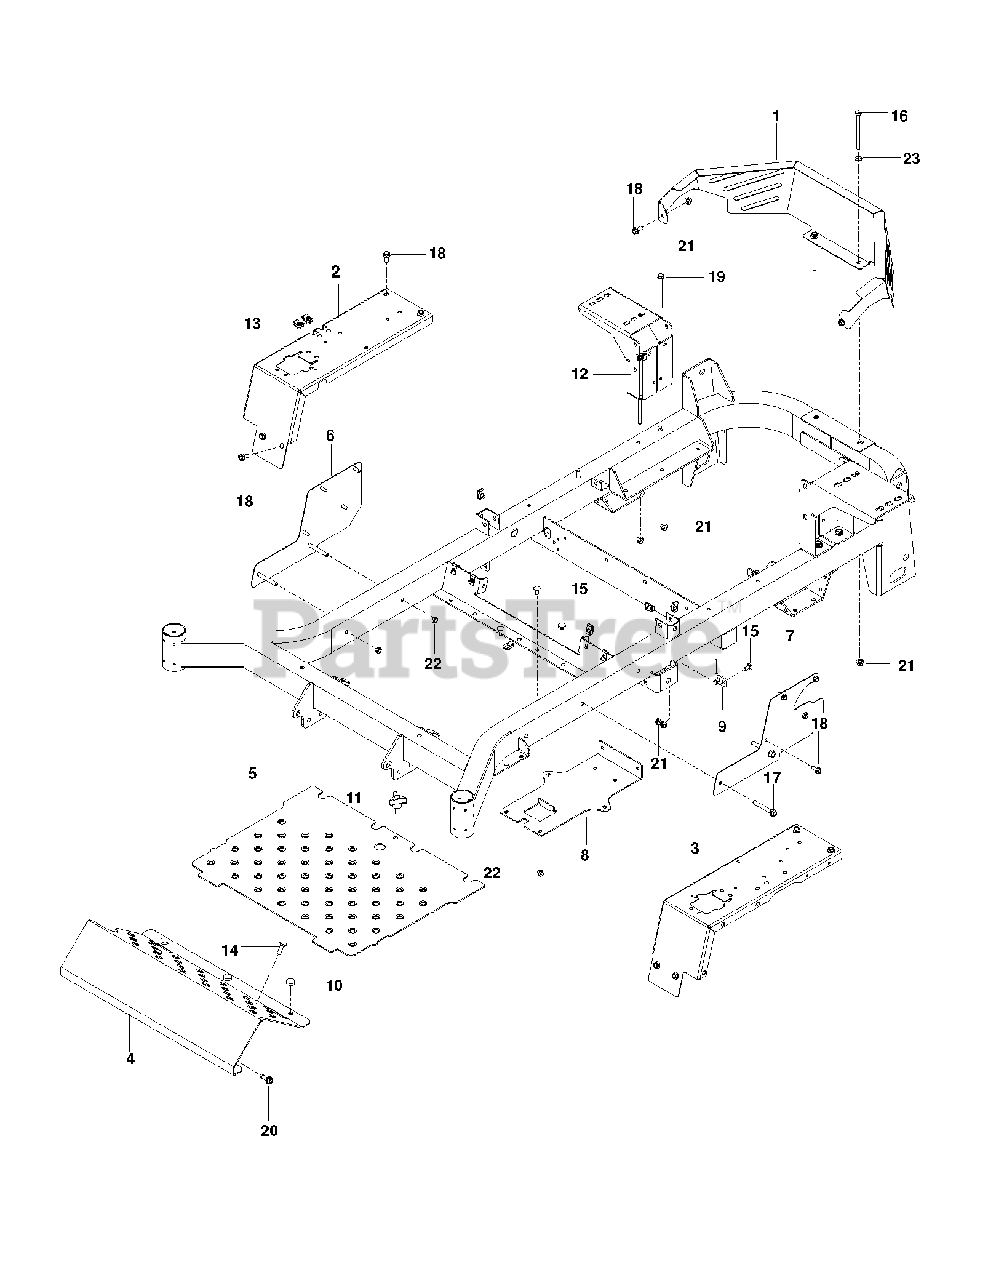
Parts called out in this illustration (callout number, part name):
1	GUARD, REAR ULTRA, BLUE
4	PLATE, FOOT REST - RAM DK BLUE
5	FLOOR PAN W/DECALS
6	SIDE, RT, BL
7	SIDE, LT, BL
8	PLATE, BATTERY, BLACK
10	GROMMET, BUMPER
11	KNOB W/STUD
12	MOUNT, TANK, ZT BLK
13	U-CLIP 5/16-18 NUT RETAINER
14	RHSNB 5/16C X 1
15	BOLT 5/16C X 3/4" CARRIAGE
16	HCS 5/16C X 4
17	HHFS 3/8-16 X 2 3/4
18	HHFS 5/16-18 X 3/4
19	HHFS 5/16-18 X 3 3/4
21	5/16-18 NYLOC FLANGE NUT
22	NUT HEX 3/8-16 NYLON, THIN
23	FLAT WASHER 5/16 SAE
